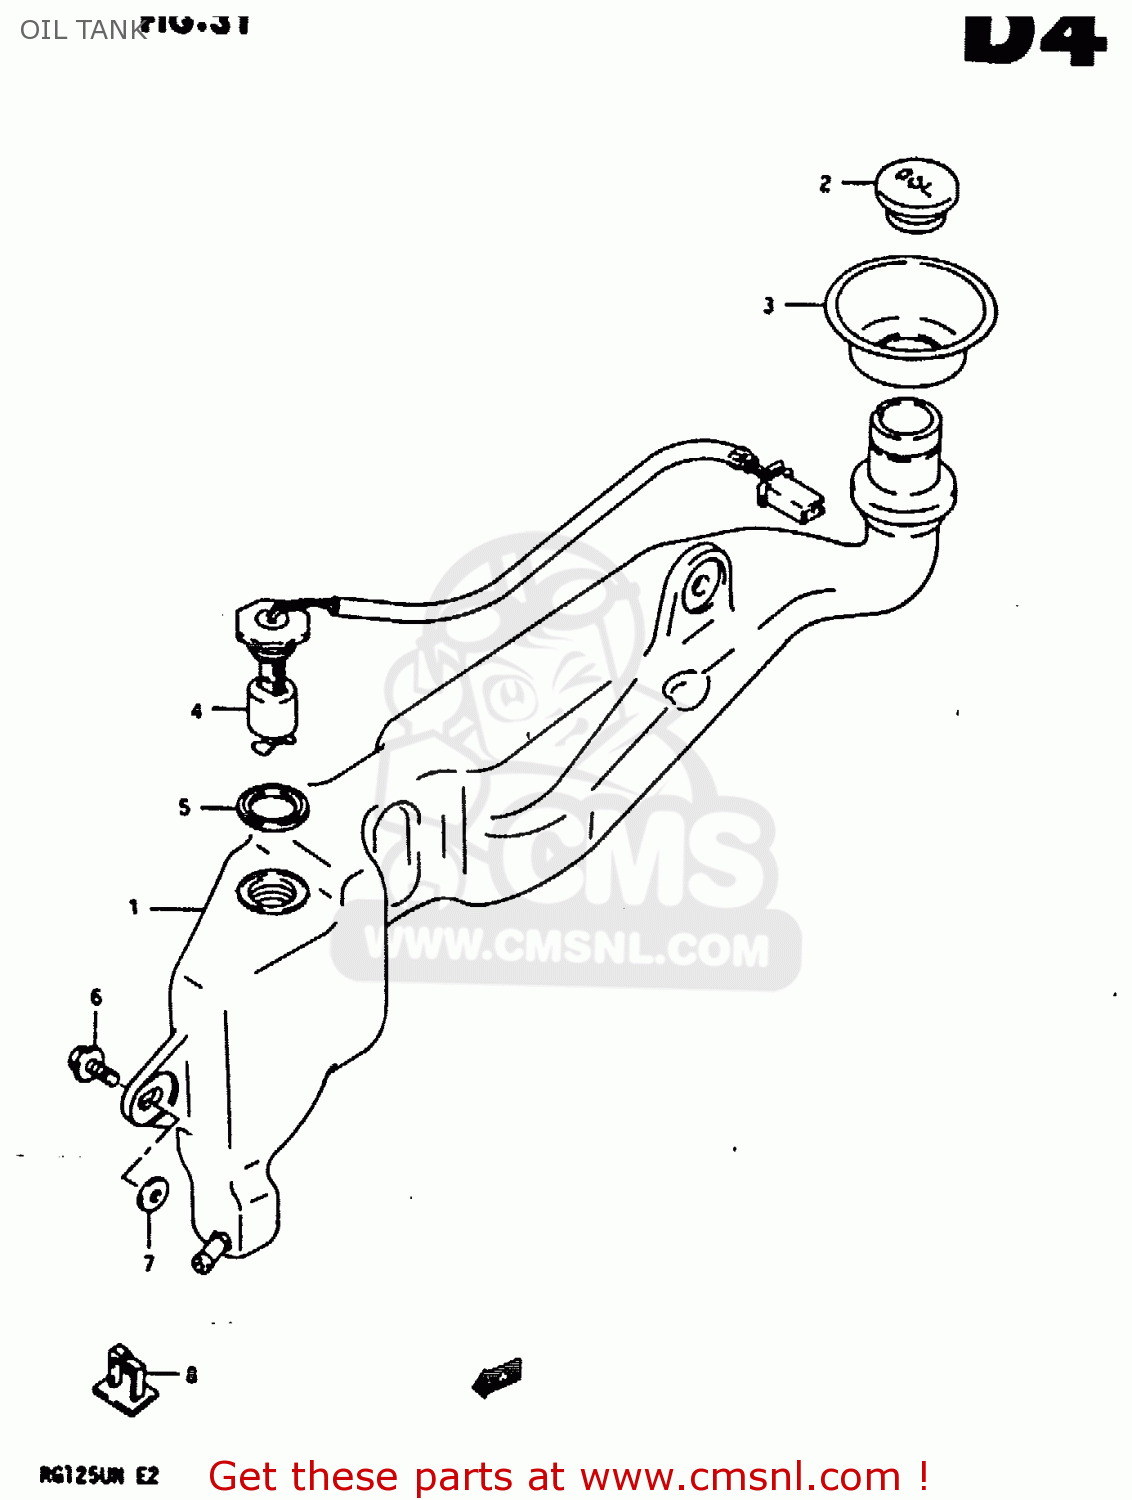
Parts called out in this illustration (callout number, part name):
1	TANK,OIL
2	CAP,OIL TANK
3	RUBBER,OIL TANK INLET
4	SWITCH ASSY, OIL LEVEL
5	GASKET (NAS)
6	BOLT(6X20)
7	WASHER(6.5X18X1)
8	CLAMP
